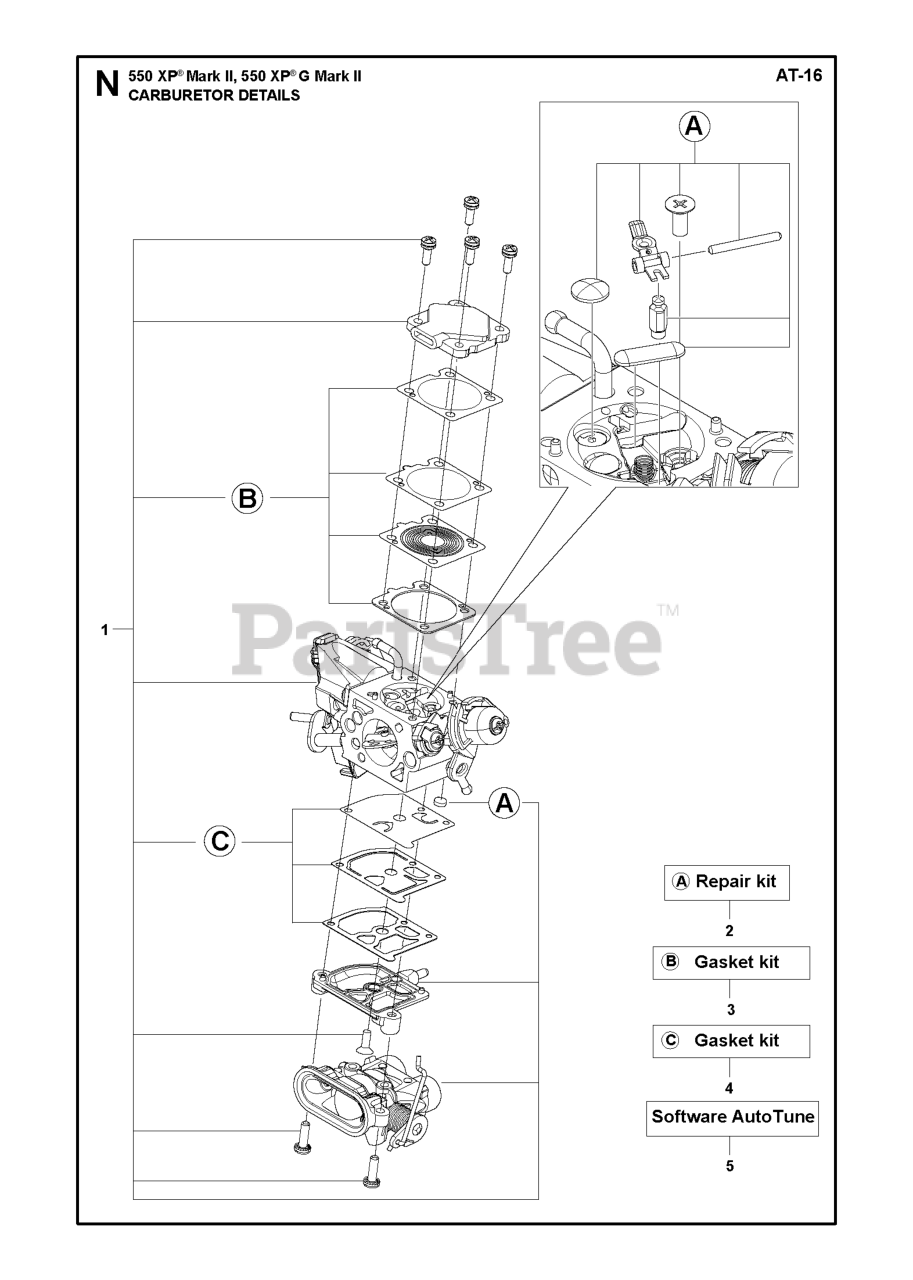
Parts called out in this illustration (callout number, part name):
1	CARBURETTOR KIT AT-16 H550XP/X
2	GASKET KIT
3	DIAPHRAGM & GASKET KIT AT SPIR
4	GASKET KIT CARBURETOR
